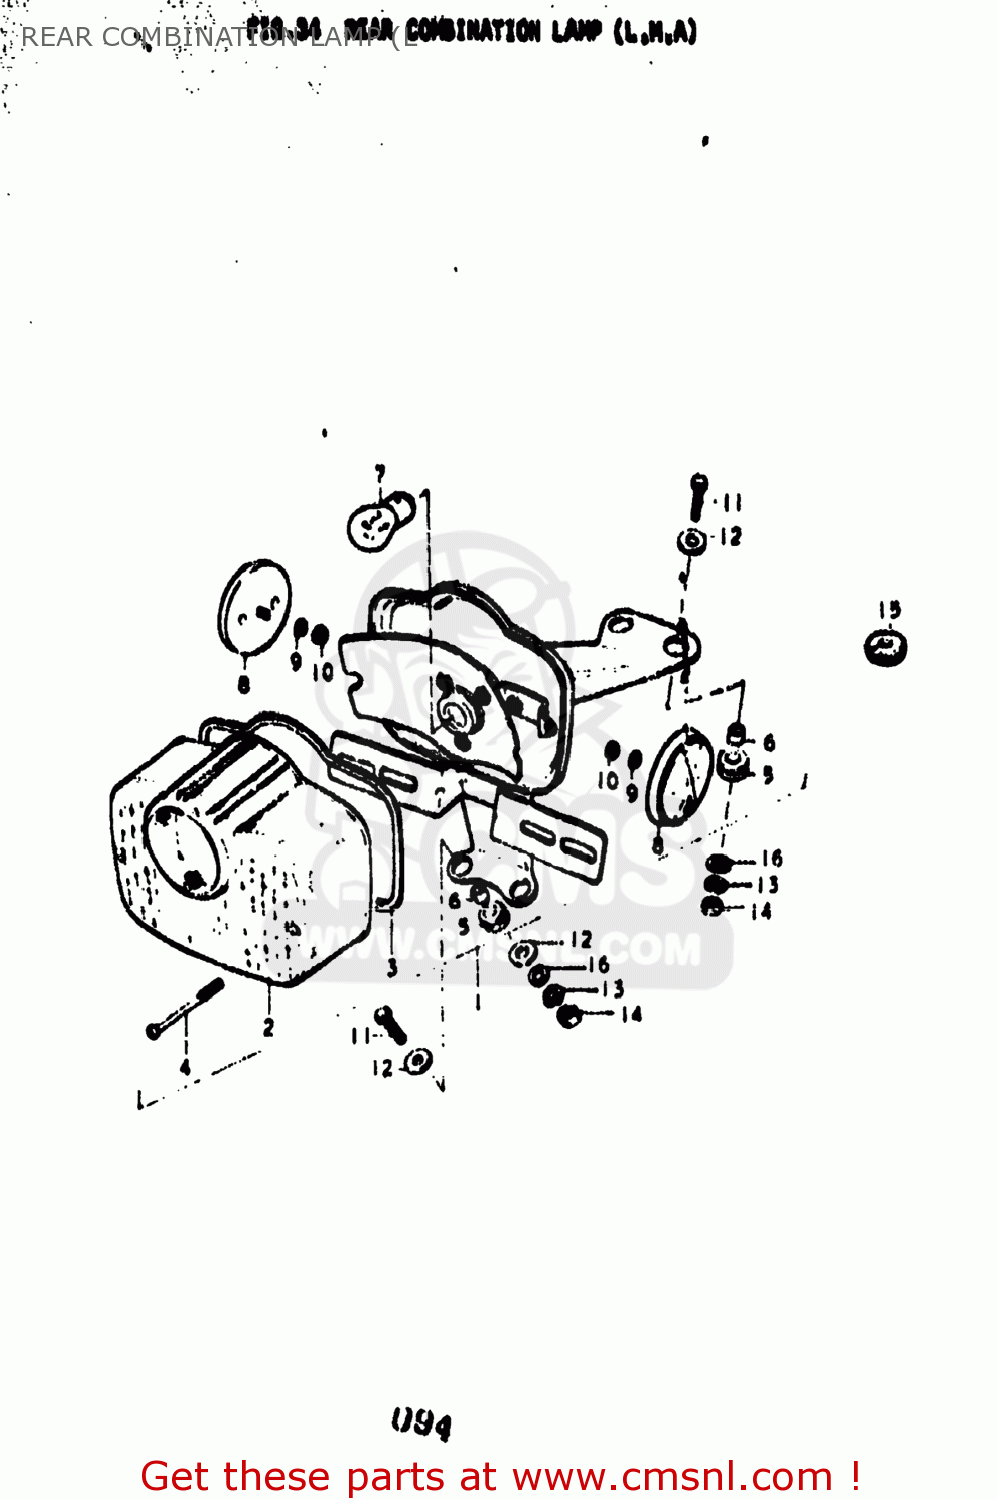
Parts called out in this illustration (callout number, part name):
1	LAMP ASSEMBLY,REAR COMBINATION
2	LENS,REAR COMBINATION LAMP
3	GASKET (NAS)
4	SCREW
5	SPACER,REAR COMBINATION LAMP
6	CUSHION
7	BULB(12V23W)
8	REFLECTOR,REFLEX
9	LOCK WASHER
10	NUT
11	BOLT
12	WASHER (6.5X20X1.2)
13	LOCK WASHER
14	NUT
15	GROMMET
16	WASHER
